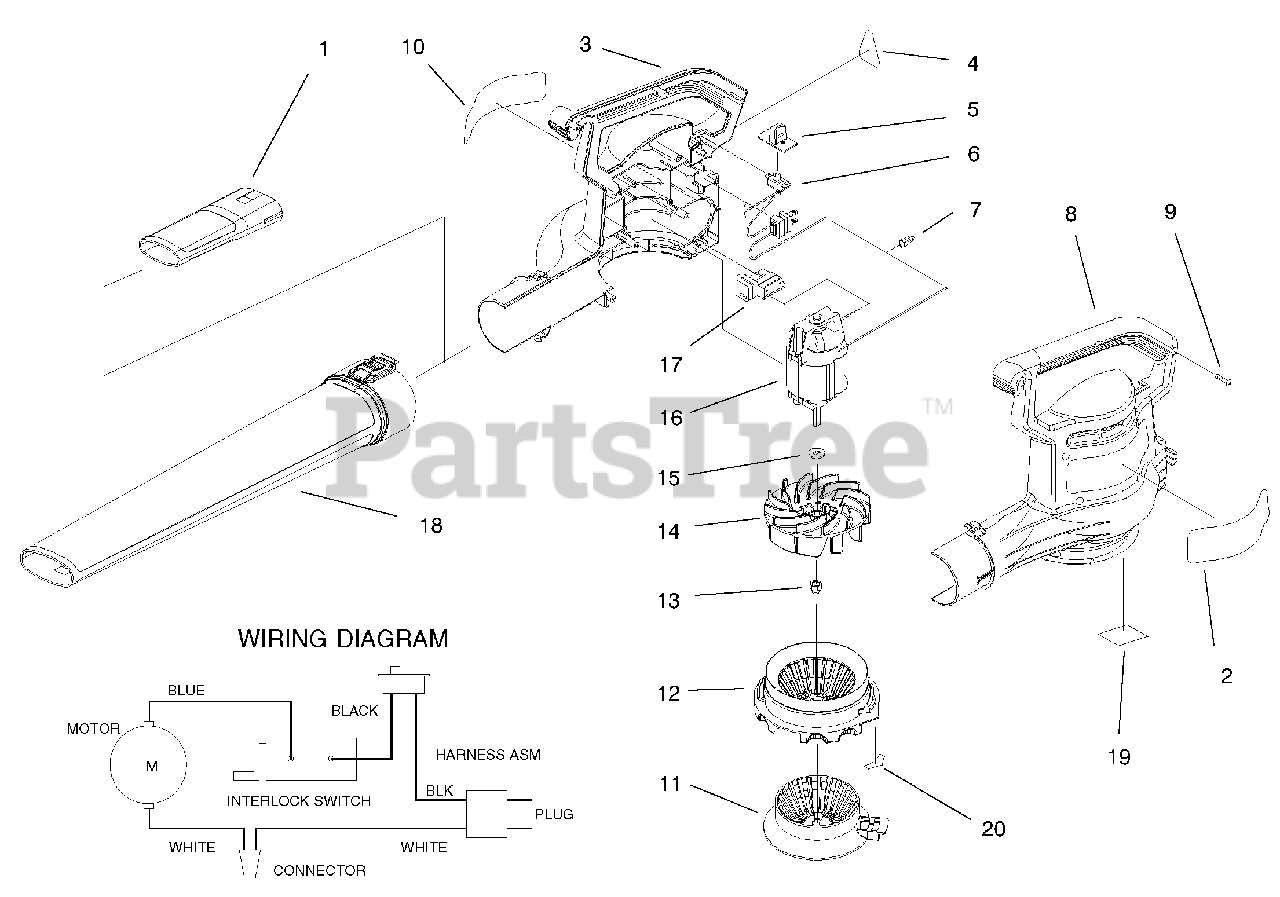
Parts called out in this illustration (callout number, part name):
1	Insert-Tube
2	Decal-Logo
3	Housing-R.H.
4	Decal-Information
5	Cover-Switch
6	Harness Assembly
7	Connector-Wire Nut
8	Housing-L.H.
9	Screw-Phillips Hd. Tap.
10	Decal-Warning
11	Choke-Air
12	Cover-Inlet
13	Nut-Cap Hex
14	Impeller
17	Switch-Interlock
18	Tube-Blower
19	Decal-Alignment, Housing
20	Decal-Alignment, Cover
